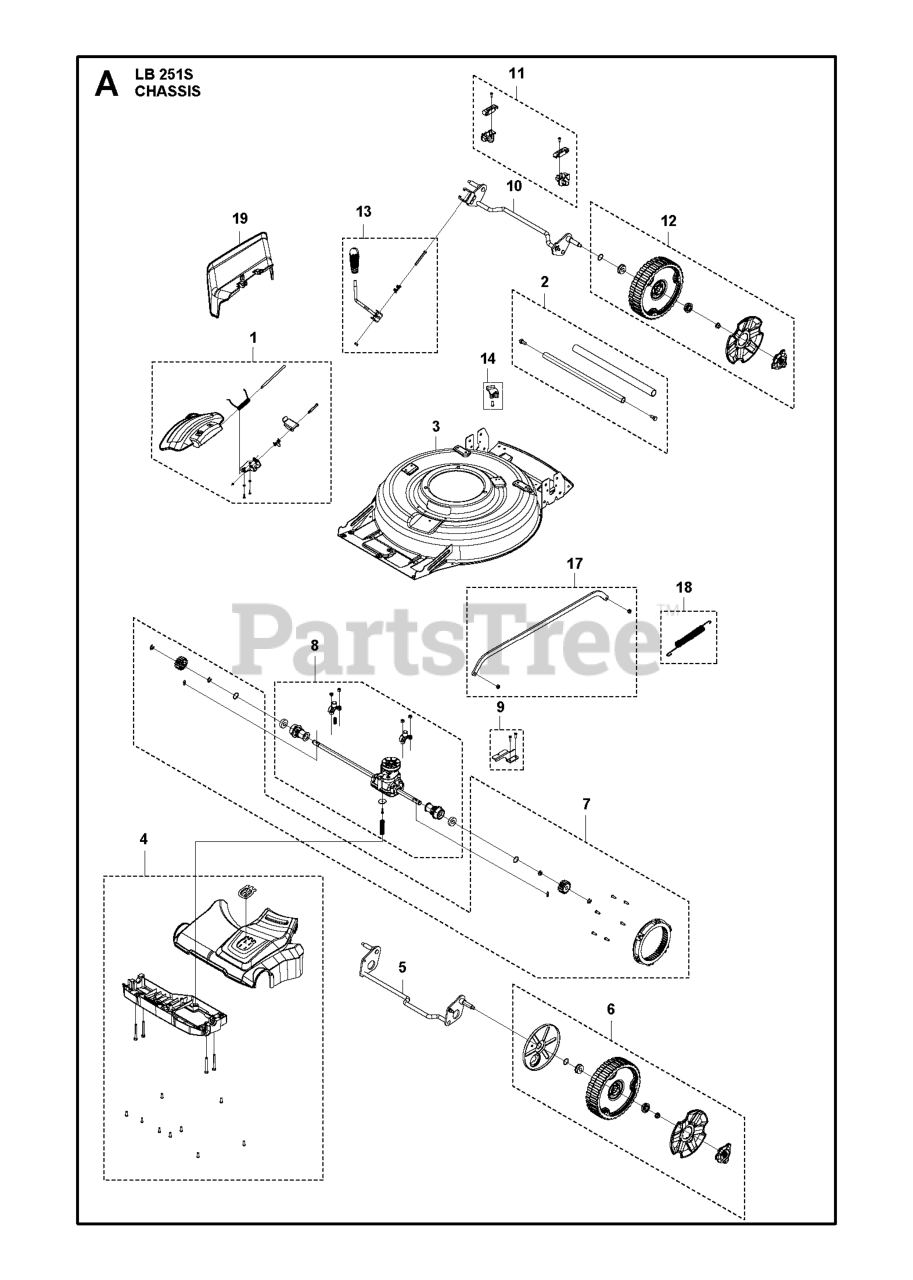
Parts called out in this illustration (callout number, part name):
1	BUMPER, MALE STUD, 1/4-20
2	PIN HAIR .148 X 2-15/16 #210
4	5/8-11 X 3-1/2 HHB GRADE 5
5	NUT.1/4-20.HEX.NYLOC.ZD
6	NUT 5/8-11 FLG NYLOC ZD
7	WASHER, 5/8 FLAT
